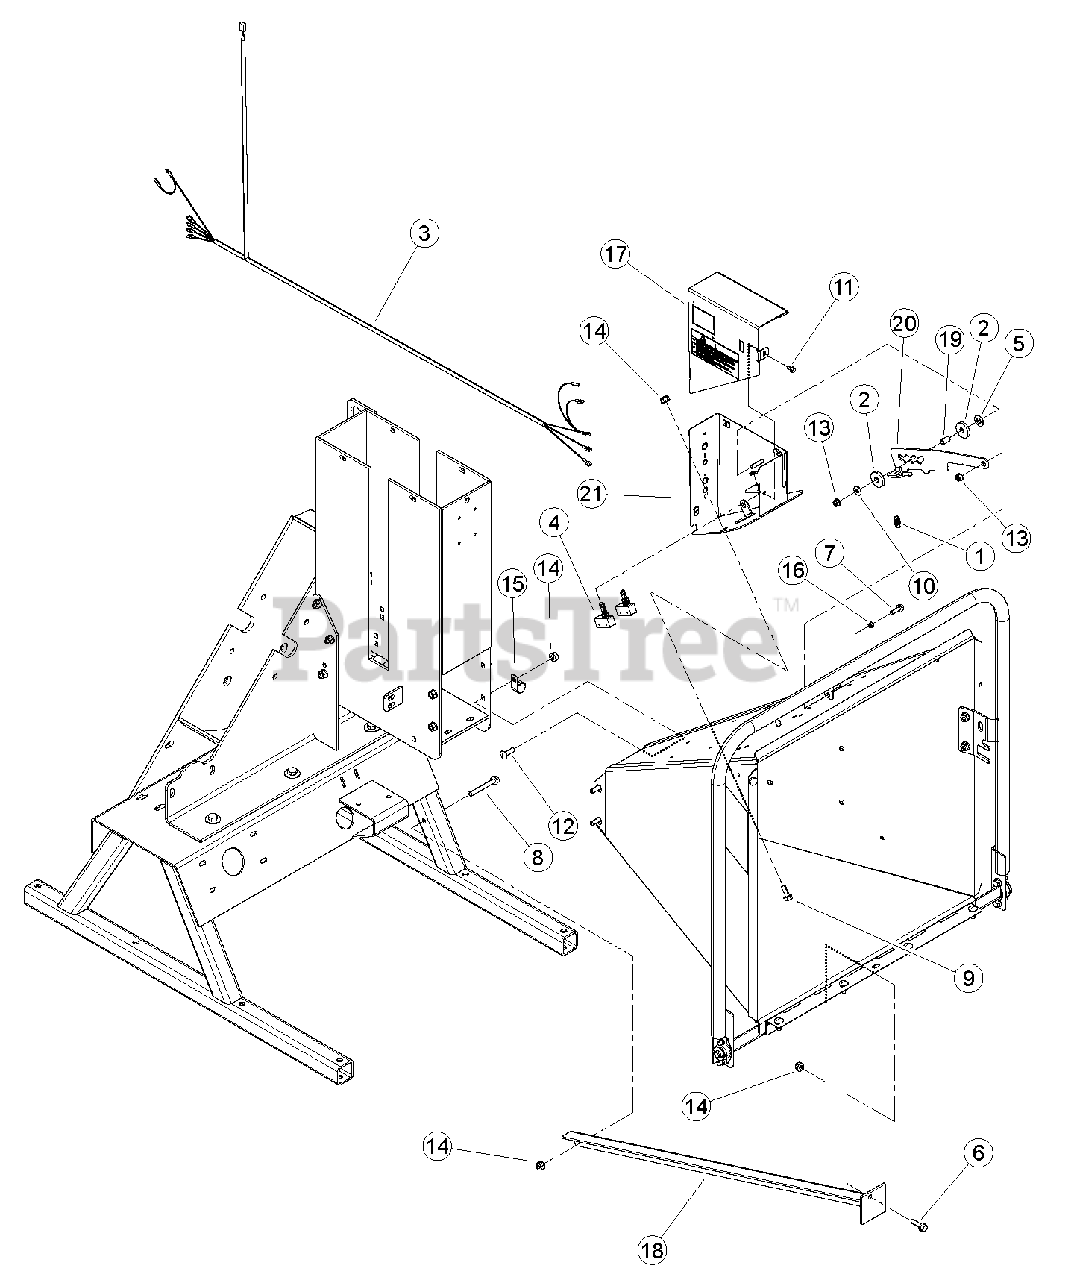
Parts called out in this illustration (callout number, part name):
1	SPRING, CONTROL BAR
2	WASHER, UHMW SPACER .515 ID-1.50 OD
3	HARNESS, FEED CONTROL
4	SWITCH, FEED CONTROL
5	WASHER, 1/2" SAE FLAT ZP
6	BOLT, 3/8 X 1-1/4 FLANGE NC
7	BOLT, 5/16 X 1 FLANGE NC
8	BOLT, 3/8 X 3 FLANGE NC
9	BOLT, 3/8 X 1 FLANGE NC
10	WASHER, 5/16" FLAT ZP
11	BOLT, 1/4 X 1/2" SERRATED FLANGE GR5 ZP
12	BOLT, 3/8 X 1-1/4" GR5 CRG NC ZP
13	NUT, 5/16-18 NYLOCK-FLANGE
14	NUT, 3/8-16 NYLOCK FLANGE
15	CLAMP, 1" COATED METAL
16	SPACER, IDLER PIVOT
17	ASSEMBLY, 5" CONTROL COVER W/ DECAL (REPLACED AND SUPERSEDED 72923-12)
18	WELDMENT, CHUTE SUPPORT
19	SPACER, .50 X .775
20	BAR, SWITCH CONTROL
21	WELDMENT, SWITCH MOUNT
